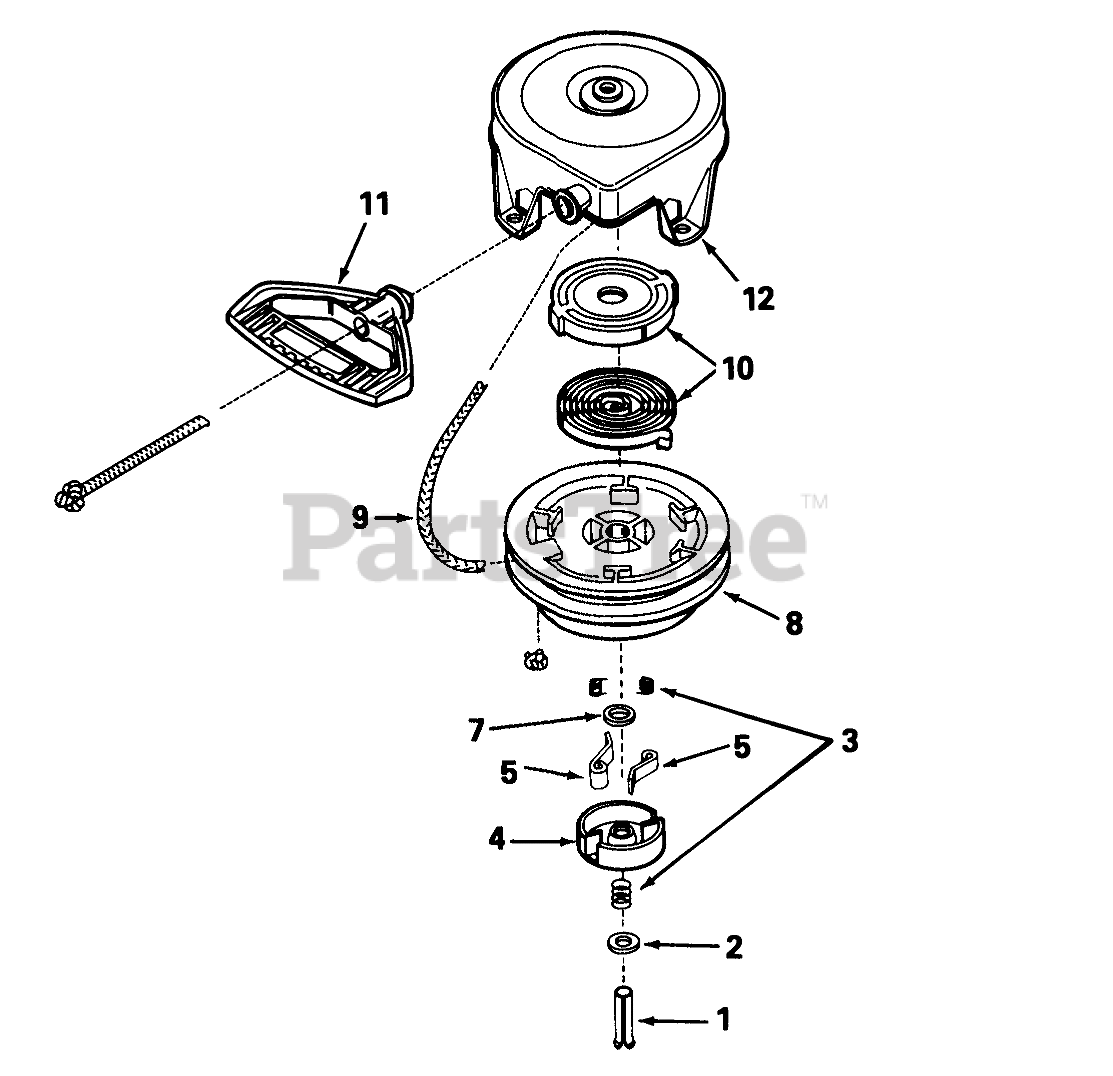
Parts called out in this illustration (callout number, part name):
1	Pin-Spring (Incl. Ref. #7)
3	Spring Assembly
4	Retainer
5	Dog-Starter
9	Rope-Starter
10	Spring & Keeper Assy.
11	Handle-Starter, Mitten Grip
12	Housing Assy., Starter
